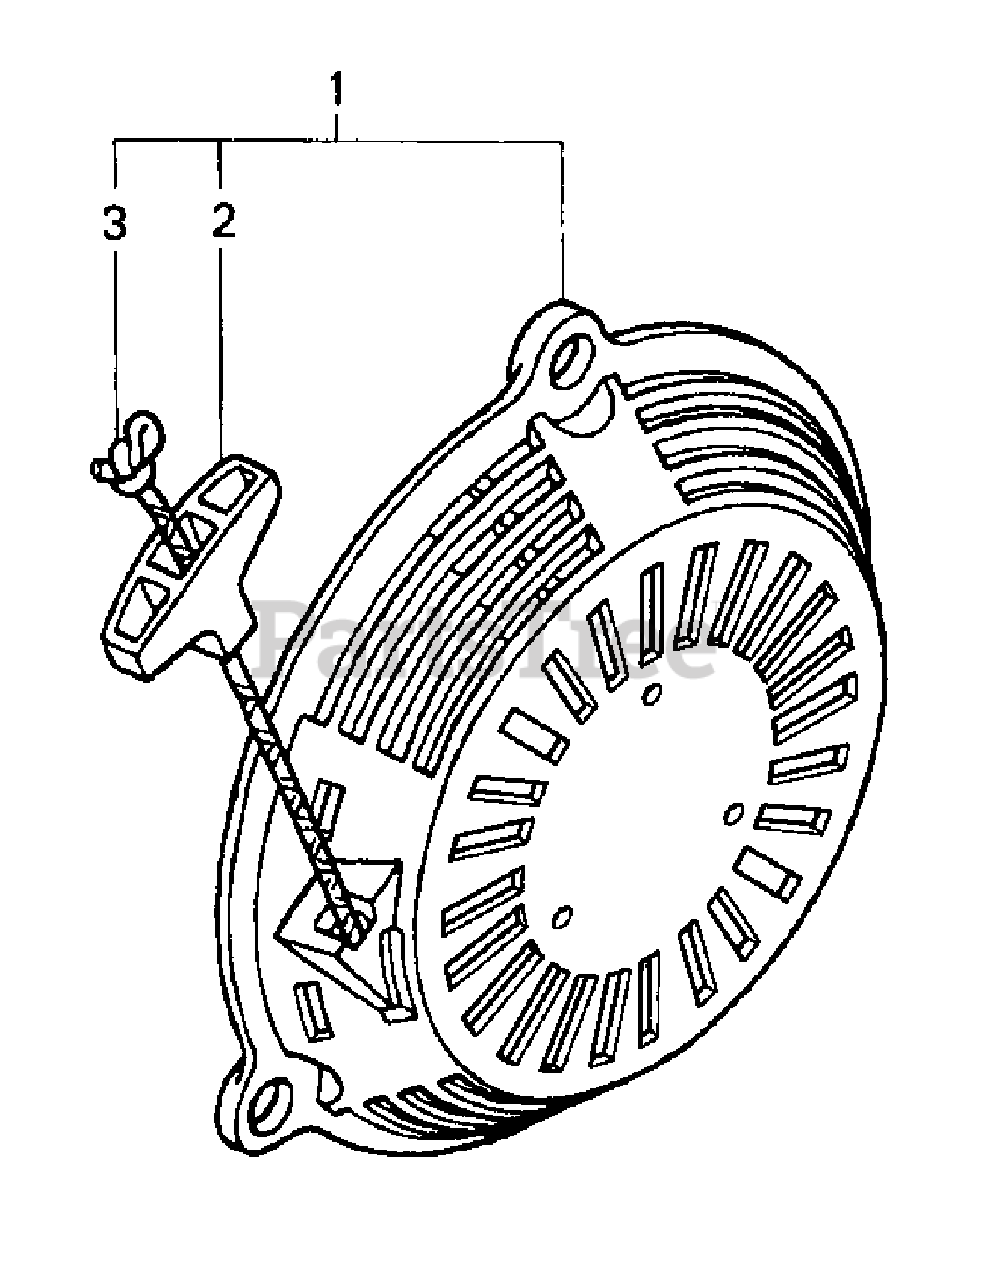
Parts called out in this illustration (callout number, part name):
1	Recoil Starter Assembly
2	Recoil Starter Knob
3	Recoil Starter Rope, #3.5 x 52"
